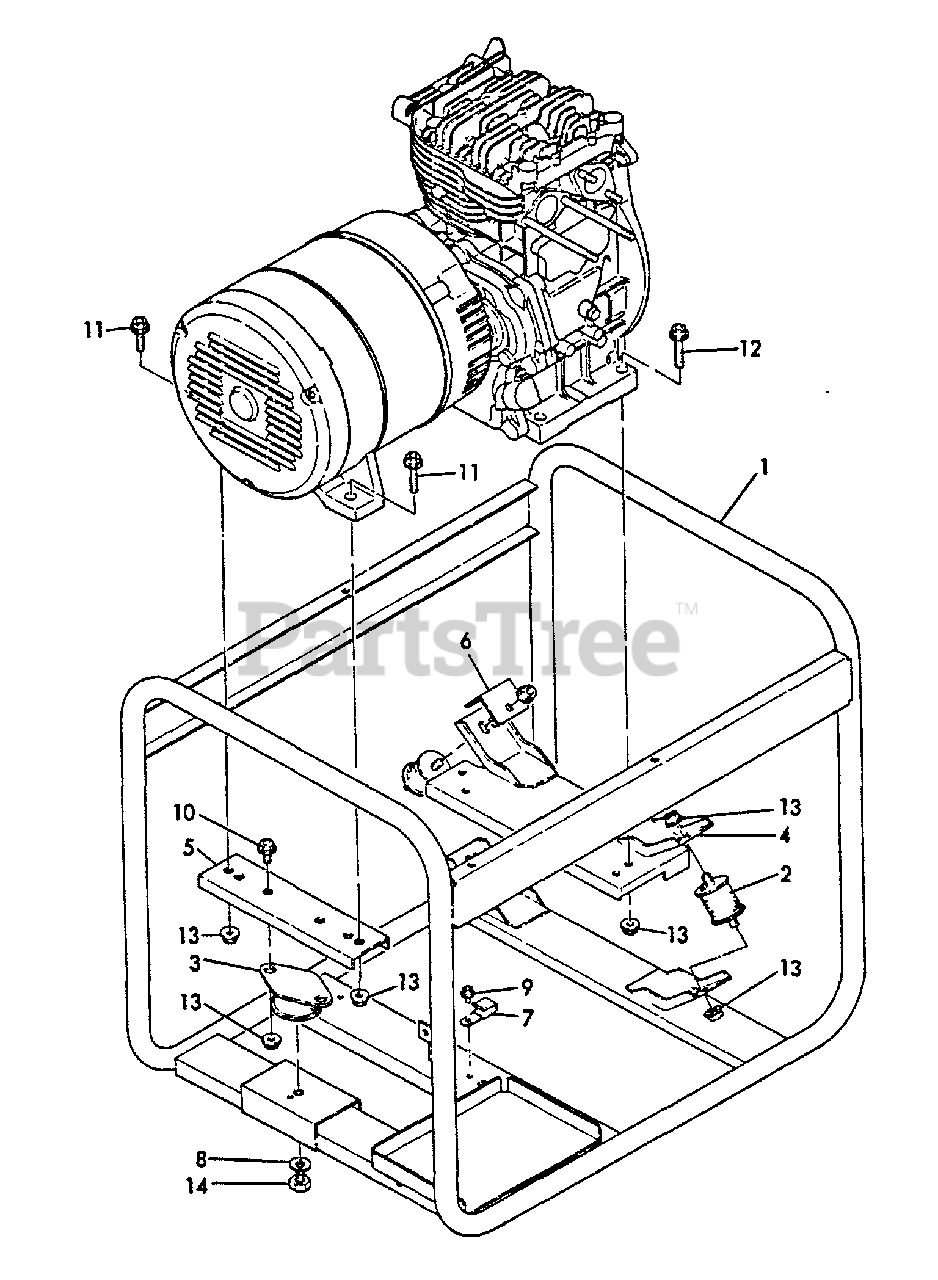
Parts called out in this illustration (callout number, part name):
1	FRAME
2	DAMPER, FRONT
3	DAMPER, REAR
4	STAY, DAMPER
5	STAY, REAR DAMPER
6	COVER, DAMPER
7	CLAMP
8	LOCKWASHER - 10
9	BOLT - 6X8 -- PLATED
10	BOLT - 8X20 -- PLATED
11	BOLT - 8X30 -- PLATED
12	BOLT - 8X38 -- PLATED
13	NUT - 8
14	NUT - 10
